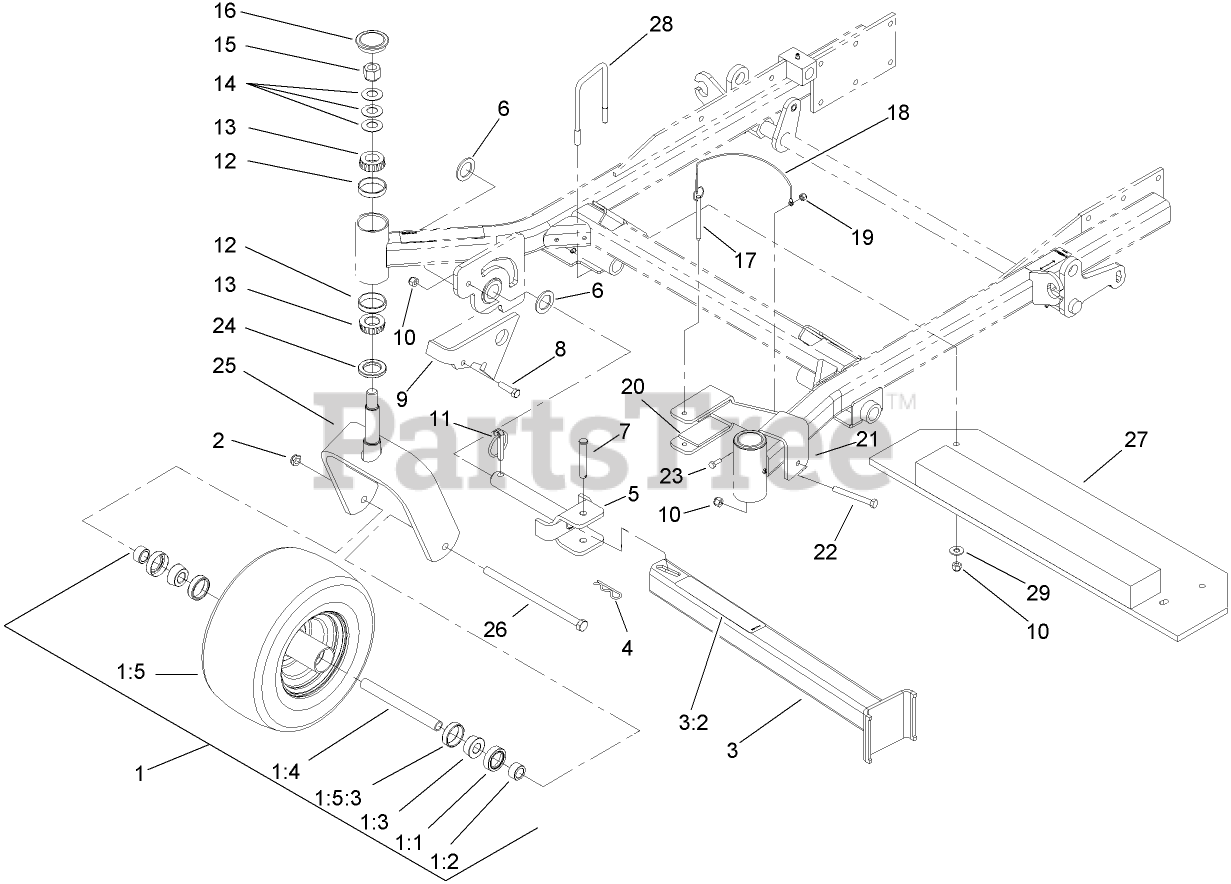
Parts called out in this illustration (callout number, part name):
1	CASTOR WHEEL ASM (SEMI-PNEUMATIC)
1:1	SEAL-BEARING
1:2	SPACER-BEARING
1:3	BEARING-CONE, TAPER
1:4	SPACER-CASTER, FRONT
1:5	WHEEL AND TIRE ASM (SEMI-PNEUMATIC)
1:5:3	BEARING-CUP
2	NUT-LOCK, NI
3	Leg ASM
3:2	DECAL-Z STAND
4	PIN-HAIR
5	PIN-PIVOT
6	WASHER-THRUST
7	PIN-CLEVIS
8	SCREW-HH
9	BRACKET-LATCH
10	NUT-LOCK, NI
11	PIN-LYNCH
12	BEARING-CUP, TAPERED
13	BEARING-CONE, TAPERED
14	WASHER-BELLVILLE
15	NUT-LOCK, NI
16	CAP-GREASE
17	PIN-HITCH, COTTERLESS
18	LANYARD-NYLON
19	NUT-LOCK, NI
20	Cushion-Rubber
21	BRACKET-CRADLE
22	SCREW-HH
23	SCREW-HH
24	SEAL-GREASE
25	CASTER
26	SCREW-HH
28	U-BOLT, 3IN
29	WASHER-FLAT
